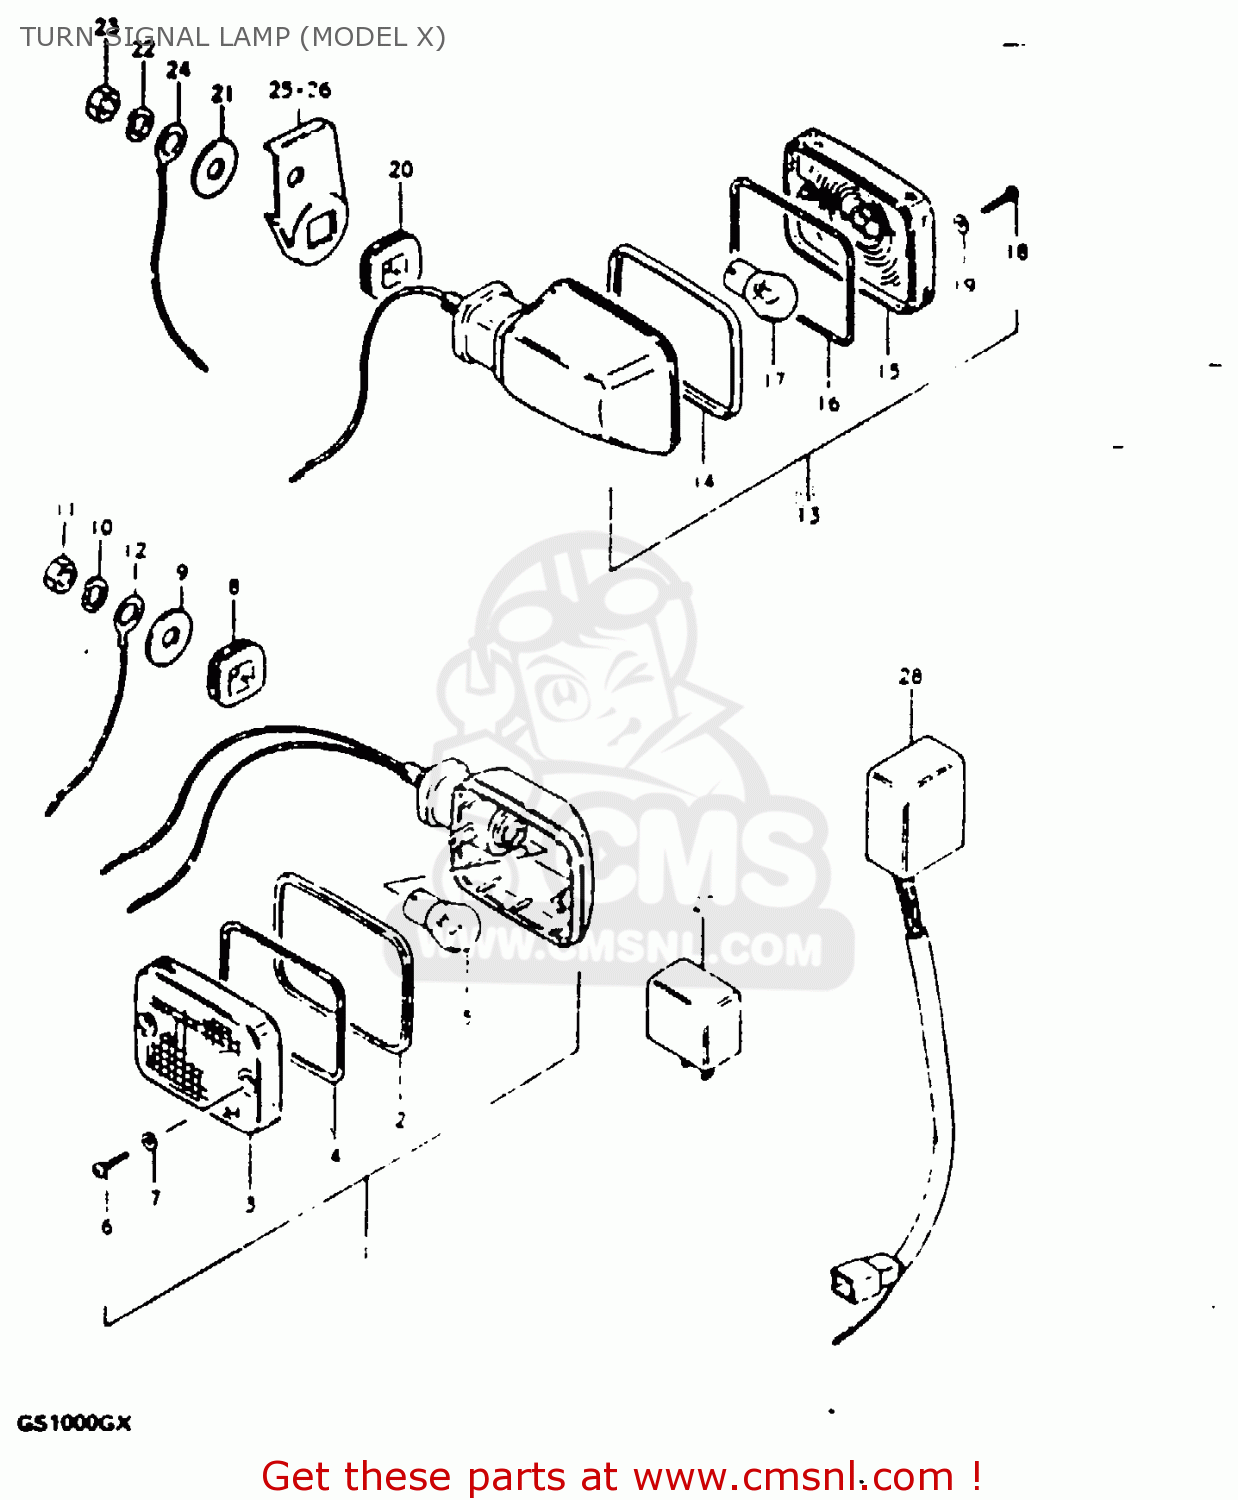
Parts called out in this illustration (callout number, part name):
1	LAMP ASSEMBLY,FRONT TURN SIGNAL
2	RIM
3	LENS
4	GASKET (NAS)
5	BULB(12V23W,STANLEY,A4577A)
6	SCREW
7	GASKET (NAS)
8	CUSHION
9	WASHER (10.5X30X2.3)
10	LOCK WASHER
11	NUT
12	LEAD WIRE,EARTH
13	LAMP ASSEMBLY,FRONT TURN SIGNAL
14	RIM
15	LENS
16	GASKET (NAS)
17	BULB(12V23W,STANLEY,A4577A)
18	SCREW
19	GASKET (NAS)
20	CUSHION
21	WASHER (10.5X30X2.3)
22	LOCK WASHER
23	NUT
24	LEAD WIRE,EARTH
25	BRACKET,RR TURNSIGNAL LAMP,R
26	BRACKET,RR TURNSIGNAL LAMP,L
27	RELAY ASSY,TURNSIGNAL
28	UNIT,TURN SIGNAL CONTROL
